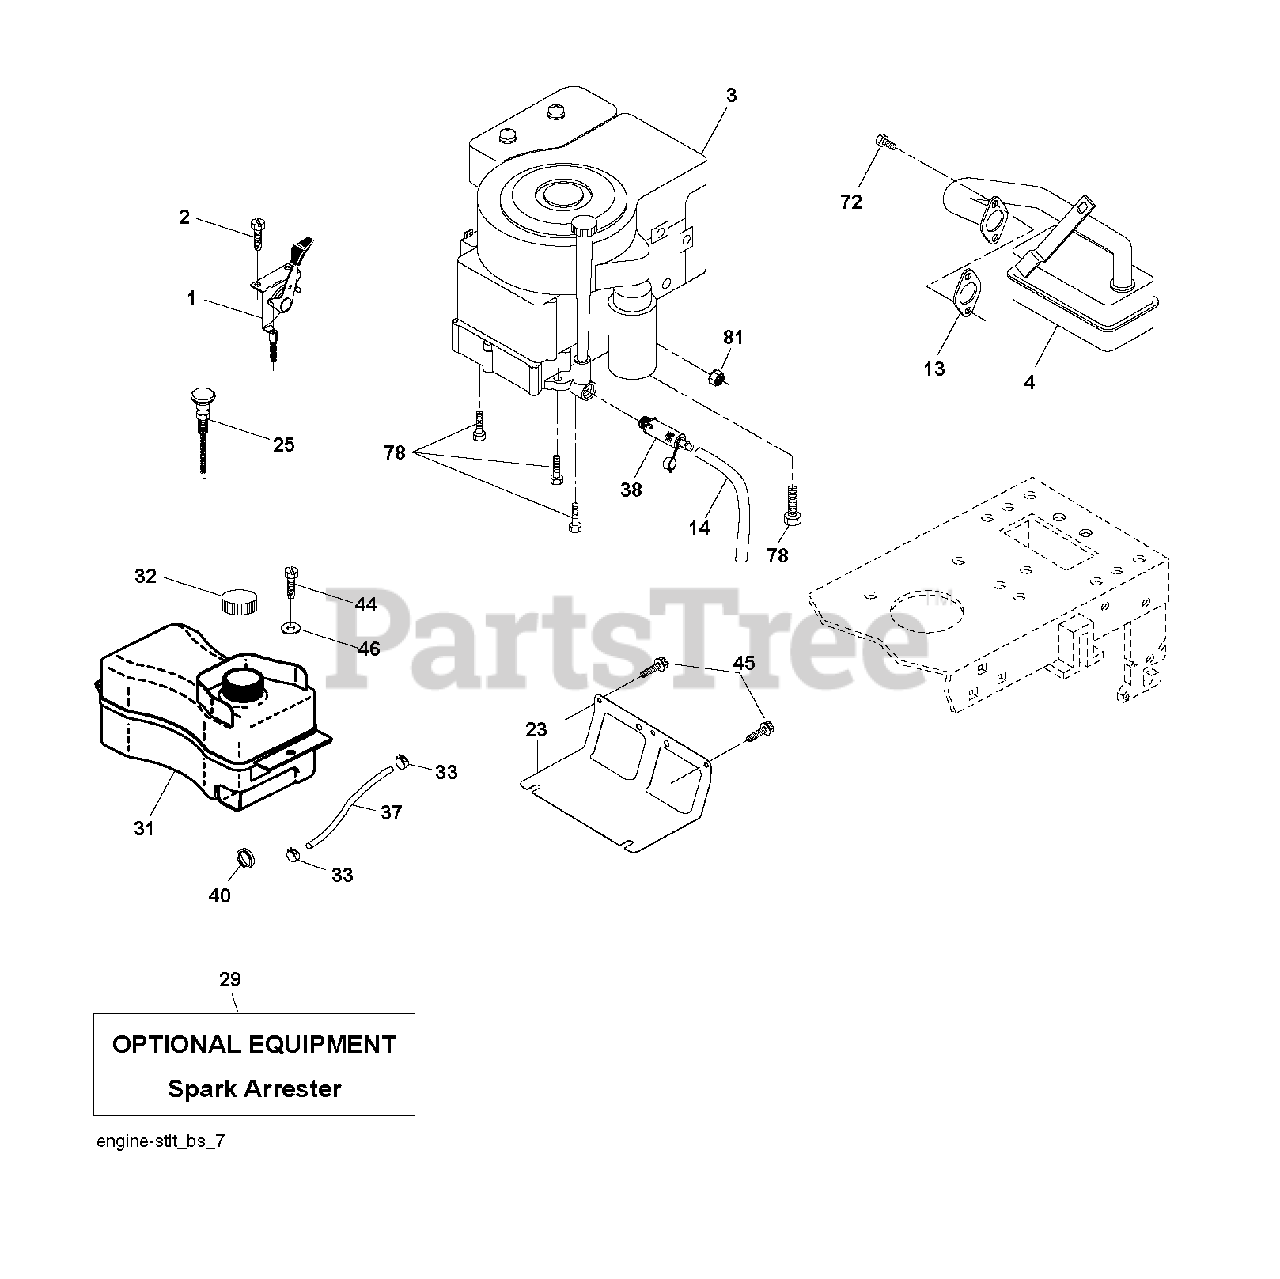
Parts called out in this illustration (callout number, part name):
1	CONTROL TH/CH FLAG
2	SCREW
13	REPL BY 532 27 22-93
14	TUBE, DRAIN OIL ASM.
23	SHEILD.BROWNING.DBR.GUARD
29	ARRESTER SPARK (OPTIONAL)
32	FUEL CAP
33	HOSE CLAMP
37	LINE.FUEL.20
38	PLUG DRAIN OIL EASY
40	GROMMET T
44	SCREW HEXWSHR 1/4-20X3/4
45	SCREW, 3/8-16X3/4
72	SCREW.SOCKET HD.5/16-1
78	SCREW.3/8-16
81	NUT
